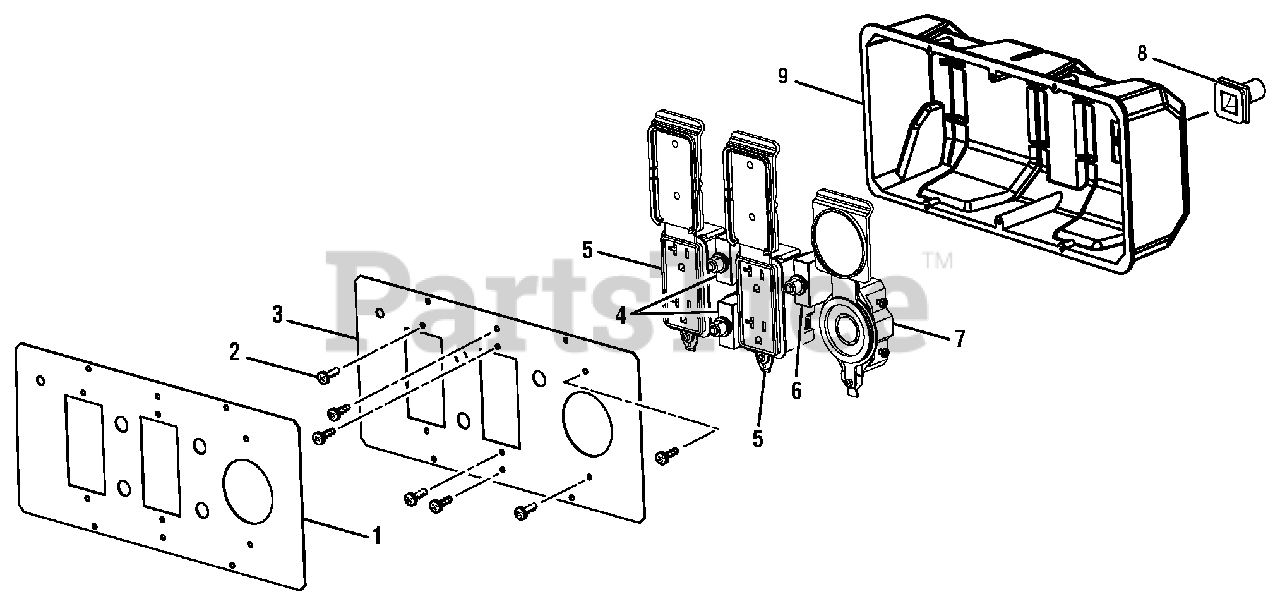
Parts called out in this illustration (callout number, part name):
1	Label (Power Outlet)
2	Screw (6-20 x 3/8 in.)
3	Front Panel
4	Circuit Breaker (20 Amp, 125 Volt)
5	120 Volt Duplex Receptacle (GFCI)
6	Circuit Breaker (30 Amp)
7	Twist Lock Receptacle (120/240 Volt, 30 Amp, L14-30R)
8	Rubber Boot
9	Control Box (Back Panel)
